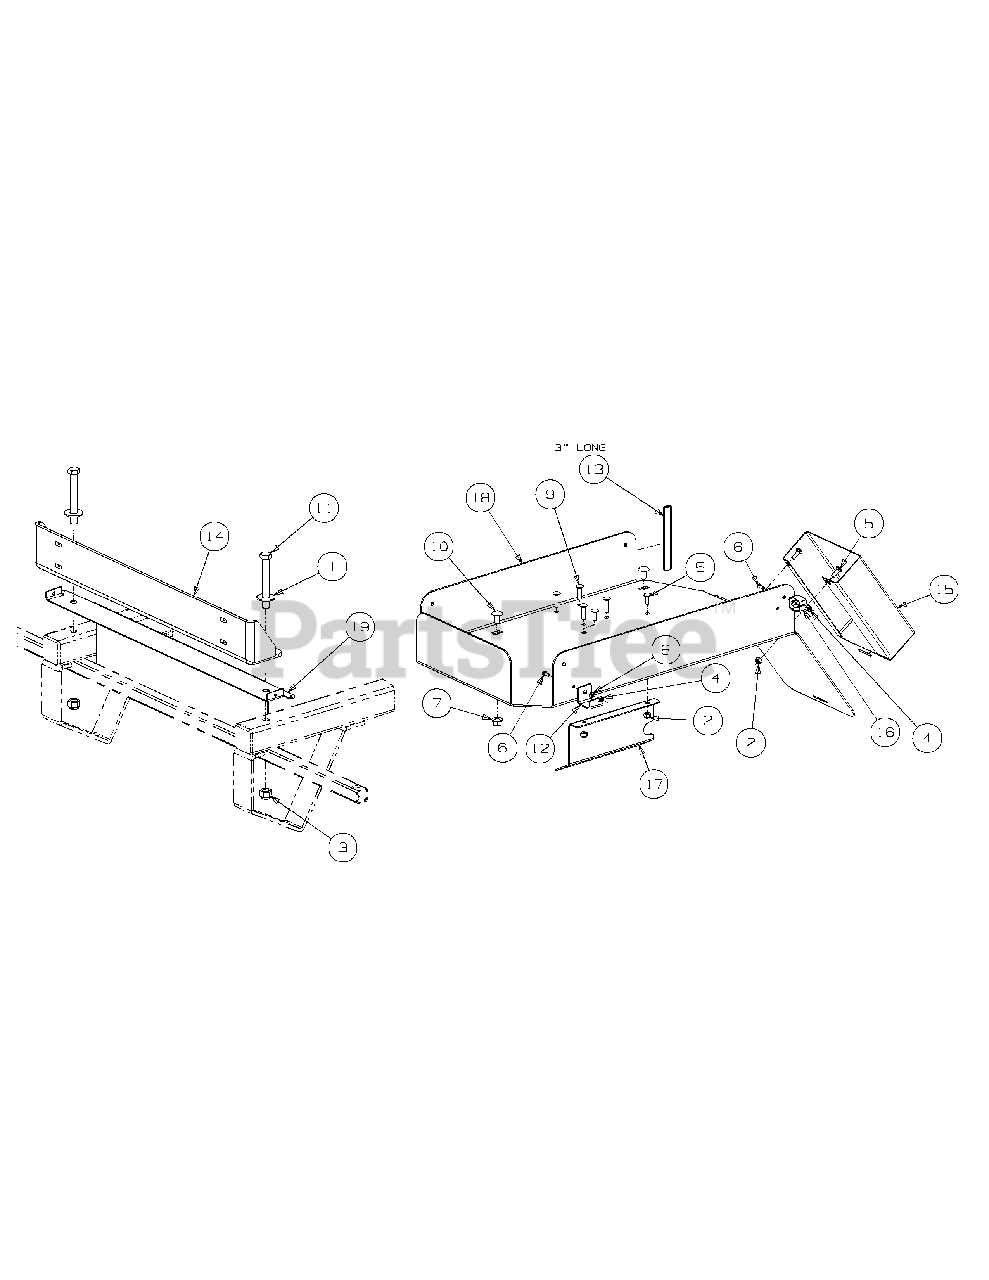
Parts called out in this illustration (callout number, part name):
1	Flat Washer, 1/2 Zinc
2	Lock Nut, Nylon Insert, 1/4-20
3	Lock Nut, Nylon Insert, 1/2-13
4	Nut, Lock, Nylon Insert, #10-32
5	Carriage Bolt, 1/4-20 x 3/4
6	Machine Screw, 10-32 x 1/2
7	Hex Nut, 3/8-16 Flange Lock
8	Flat Washer, #10, SS
9	Carriage Bolt, 1/4-20 x 1.00
10	Carriage Bolt, 3/8-16 x 0.75 Long
11	Hex Head Capscrew, 1/2-13 x 4.00
12	Stop Bracket
13	Battery Edge Trim
14	Rear Spray Bumper
15	Spray Wand Hose Holder
16	Tool Holder
17	Electric Pump Cover
18	Pump Motor Plate
